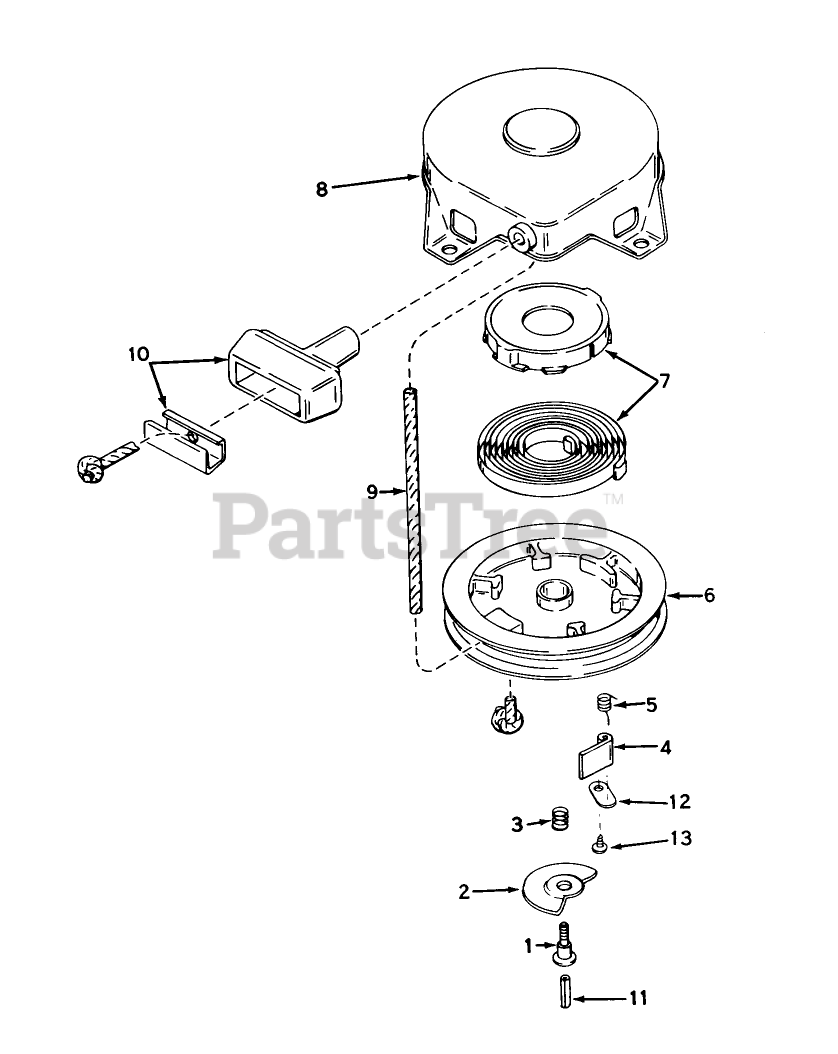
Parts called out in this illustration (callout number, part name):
1	Screw
2	Cam-Dog
3	Spring-Brake
4	Dog-Starter
5	Spring-Dog
6	Pulley
7	Spring Keeper Assy.
8	Housing Assy., Starter (Incl. #1)
9	Rope-Starter
10	Assy., Starter
11	Centering
12	Retainer-Dog
13	Screw
